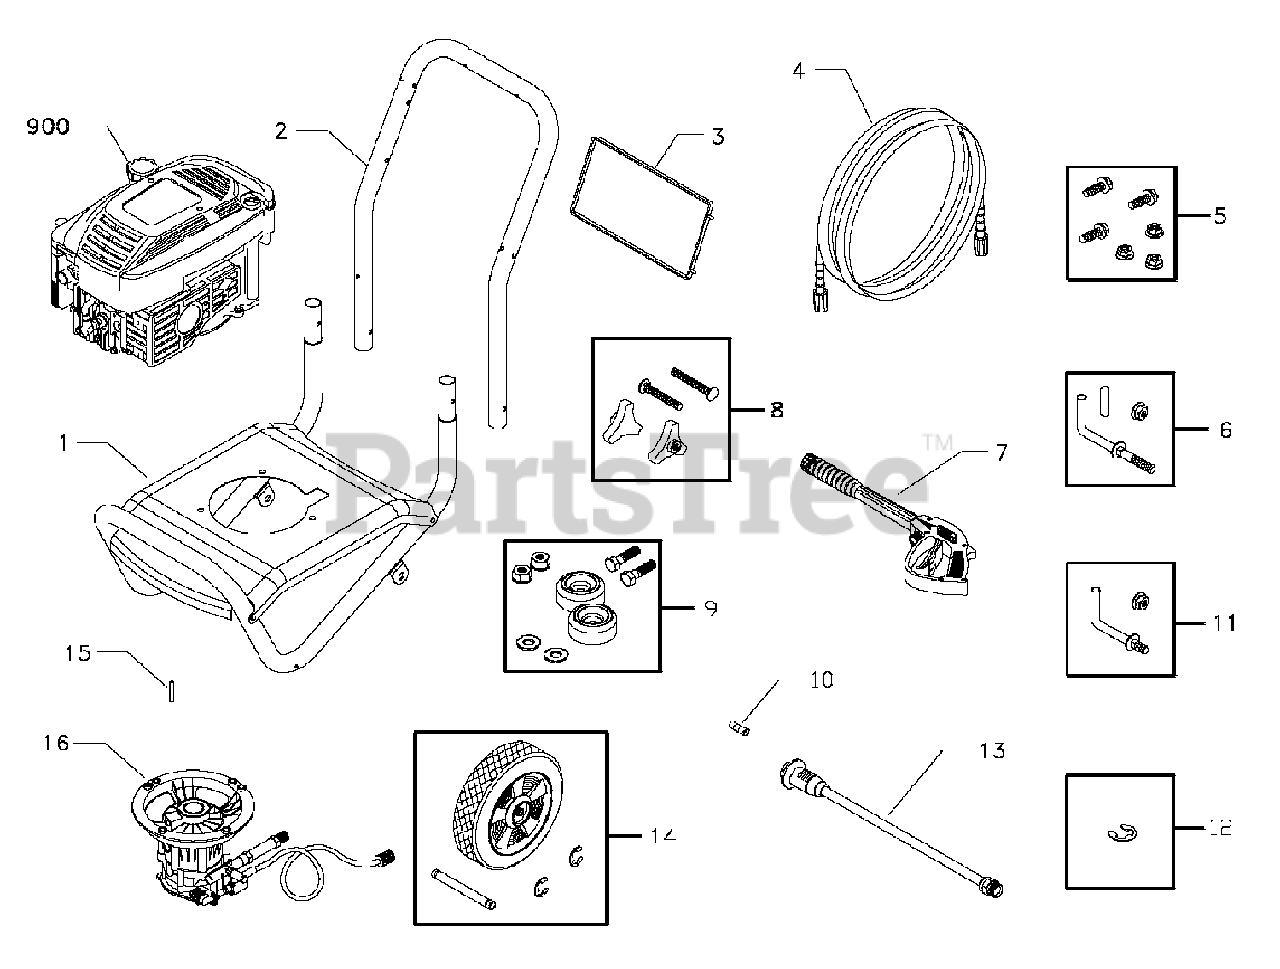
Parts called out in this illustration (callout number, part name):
1	BASE
3	BILLBOARD
4	HOSE
5	KIT, Pump Mounting Hardware
6	KIT, Hook
8	KIT, Handle Connector
9	KIT, Vibration Mount
10	ORIFICE
11	KIT, Hook
12	KIT, E-Ring
13	WAND, Adjustable Nozzle
14	KIT, Wheel
16	ASSY, Pump
900	§ ENGINE
